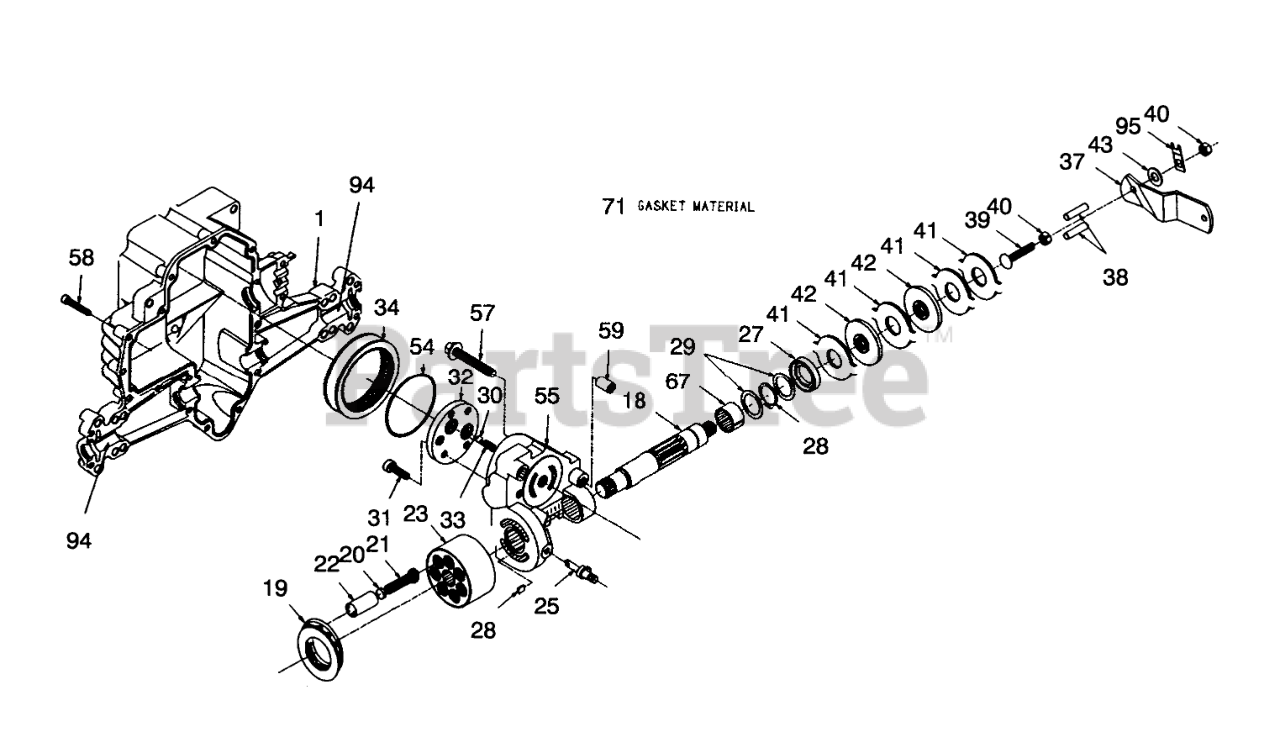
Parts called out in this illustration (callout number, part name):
1	Housing-Lower
18	Shaft-Motor
20	Seat-Piston Spring
21	Spring-Piston
23	Block-Cylinder (Motor)
25	Actuator-Bypass
26	Plate-Bypass
27	Seal-Lip
29	Washer
30	Ball
31	Spring-Check Valve
32	Plate-Check Valve
33	Socket Hd. Cap Screw
34	Oil Filter Element
37	Lever-Brake
38	PIN - ACTUATING
39	Bolt
40	NUT-LOCK, NI
41	Stator-Brake
42	Rotor-Brake
43	WASHER-PIVOT
54	O Ring
55	Center-Section
57	Bolt
58	Bolt
67	Du Bearing
71	Gasket Material
94	Grease Durina "O"
95	STRAP - LOCKING
